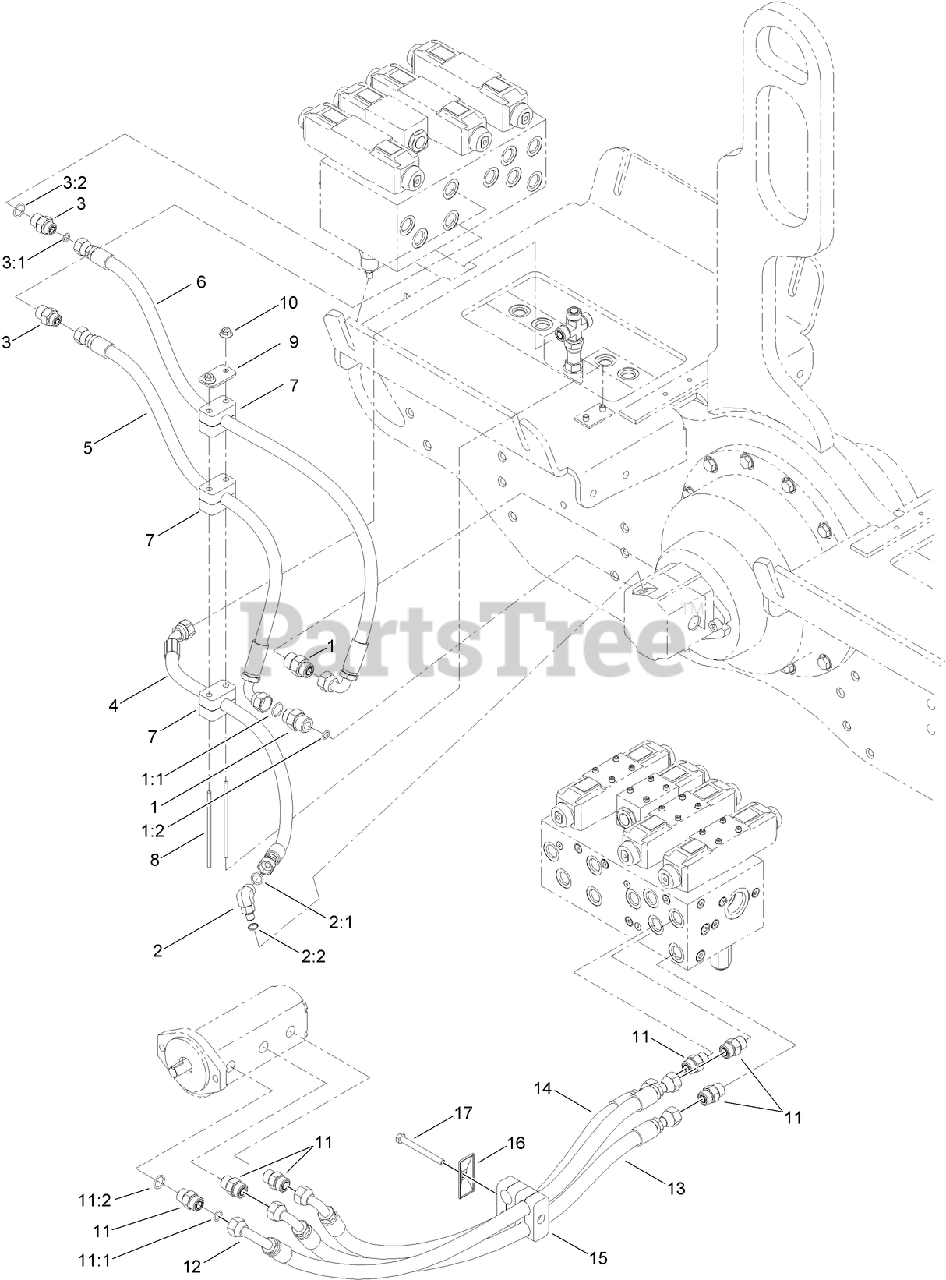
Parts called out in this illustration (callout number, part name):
1	FITTING-STRAIGHT
1:1	O-RING
1:2	O-RING
2	FITTING-ELBOW 90
2:1	O-RING
2:2	O-RING
3	FITTING-STRAIGHT
3:1	O-RING
3:2	O-RING
4	HOSE ASM
5	HOSE ASM
6	HOSE ASM
7	CLAMP-HOSE
8	ROD-THREADED
9	COVER-PLATE
10	NUT-HEX FLANGE
11	FITTING-STRAIGHT
11:1	O-RING
11:2	O-RING
12	HOSE ASM
13	HOSE ASM
14	HOSE ASM
15	CLAMP-HOSE, DUAL HOSE
16	COVER-PLATE, DUAL HOSE
17	SCREW-HH
